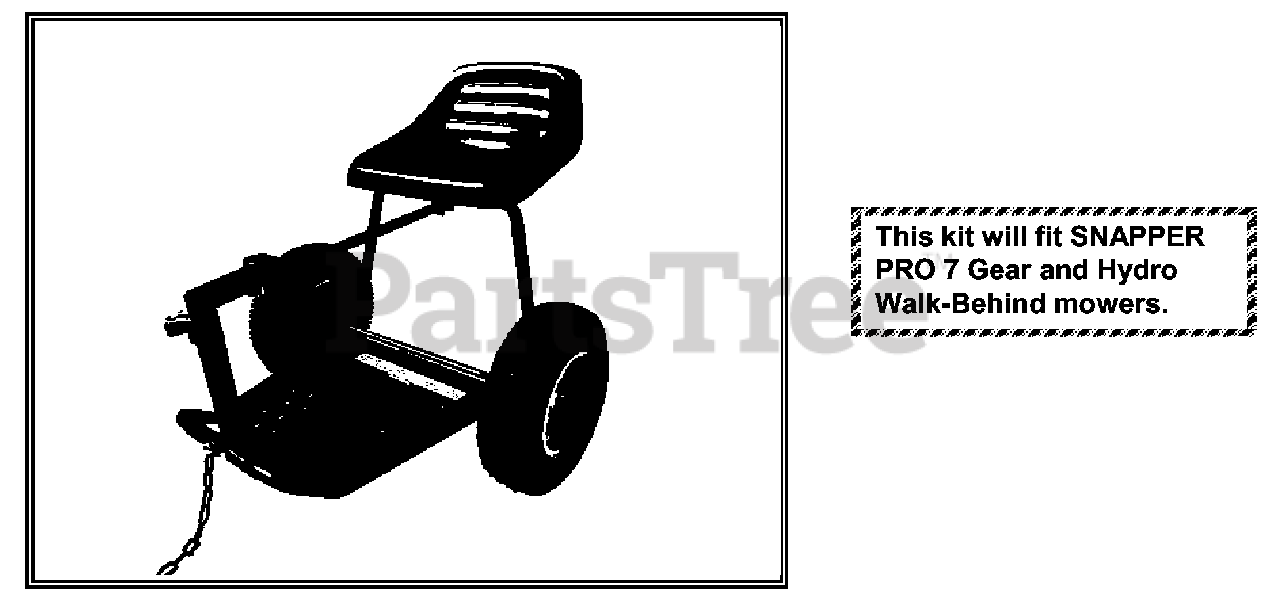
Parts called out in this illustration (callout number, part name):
1	ASSEMBLY, Wheel
2	TUBE, Seat Support
3	BRACE, Draw Bar
4	WELDMENT, Seat Adjust
5	WELDMENT, Channel Brace
6	Ass'y, Drawbar/Hitch
7	HOOK (5/16-18 thread)
8	SPRING, 3/4" O.D. x 1-1/2"
9	HITCH
10	DRAWBAR
11	NUT, 3/8-16 Hex Nyloc
12	WASHER, 5/16" Flat
13	WASHER, 3/8" Flat
14	BOLT, 3/8-16 x 2-1/4"
15	NUT, 5/16-18 Hex Nyloc
16	SEAT (with 19295 Decal)
17	WELDMENT, Frame
18	WASHER, 1" I.D. Flat
19	WASHER, Special
20	SPACER, Seat
21	KNOB (5/16-18 thread)
22	SPACER, Axle
23	PIN, 1/2 x 1-3/16" Clevis
24	CHAIN, Hitch
25	CLAMP
26	HITCH, Bottom
27	HITCH, Top
28	LEVER, Shift Sulky
29	SADDLE
30	GRIP, Adj. Lever
31	SCREW, 5/16-18 x 3/4" Hex Head Cap, Grade 5
32	SCREW, 5/16-18 x 2-1/4" Hex Head Cap, Grade 5
33	NUT, 3/8-16 Hex Nyloc
34	PIN, Lynch
35	WASHER, 5/16" Split Lock
36	WASHER, 1/2" Flat
37	PIN, 1/8 x 1-1/2" Cotter
38	PIN, 5/32 x 1" Cotter
39	SCREW, 3/8-16 x 1" Hex Head Cap, Grade 5
40	SCREW, 3/8-16 x 2" Hex Head Cap, Grade 5
41	SCREW, 5/16-18 x 1-3/4" Hex Head Cap, Grade 5
42	BOLT, 5/16-18 x 2" Hex, Grade 5
43	BOLT, 5/16-18 x 2-1/2" Sq. Neck Carriage, Grade 5
44	NUT, 1/2-13 Hex Center Lock, Grade 5 or B
45	SCREW, 5/16-18 x 2-1/2" Hex Head Cap, Grade 5
46	BOLT, 1/2-13 x 1-3/4" Bolt, Grade 5
47	INSTRUCTIONS
